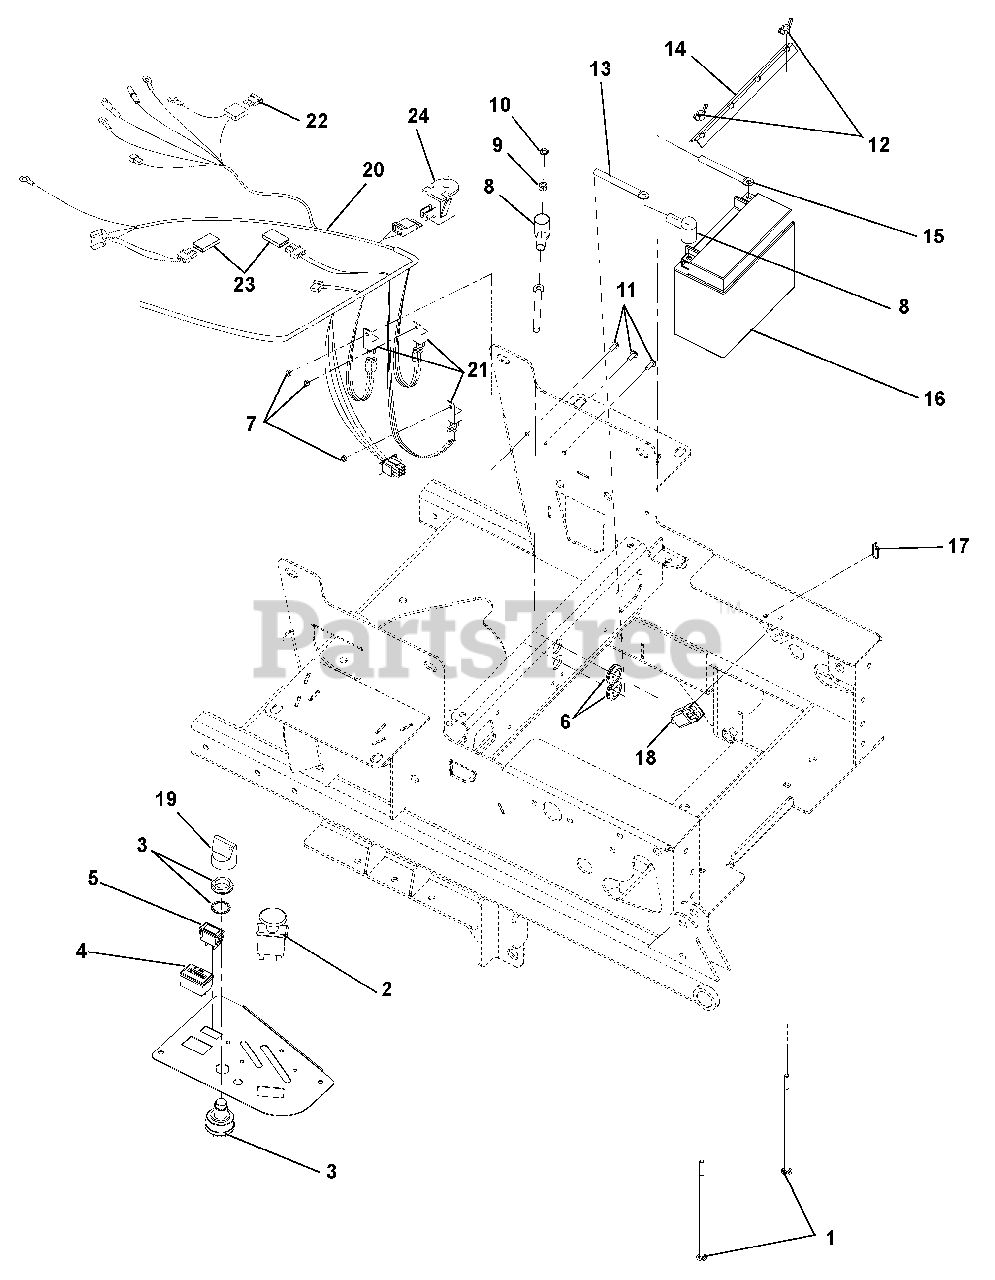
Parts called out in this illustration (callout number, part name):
1	Bolt, Round Head Square Neck .25-20 x 7.50
2	Switch, Clutch
3	Switch, Ignition
4	Hour Meter- Digital
5	Light, Indicator
6	Grommet, Rubber 5/8 ID/1.13
7	Nut, Locking-Nylon 10-24 with Insert
8	Boot, Eyelet Terminal
9	Nut, Hex .25-20
10	Washer, Locking-EXT.262 x .502 x .026
11	Screw, Machine 10-24 x .50 Hex Washer Head
12	Nut, Locking Wing .250-20
13	Cable, Positive Battery 26.00"
14	Hold Down
15	Cable, Negative Battery .25 x 20.00 x .3
16	Battery, 12 Volt Sealed AGM
17	Cable Tie
18	Switch, Snap In- N.O./N.O.
19	Key, with Shield
20	Harness, Wire- IZ, CZ, 100I
21	Relay,Sealed w/Diode
22	Fuse, 30 AMP.
23	Diode, Connector Shell
24	Switch, Snap Mounting (N.O.)
